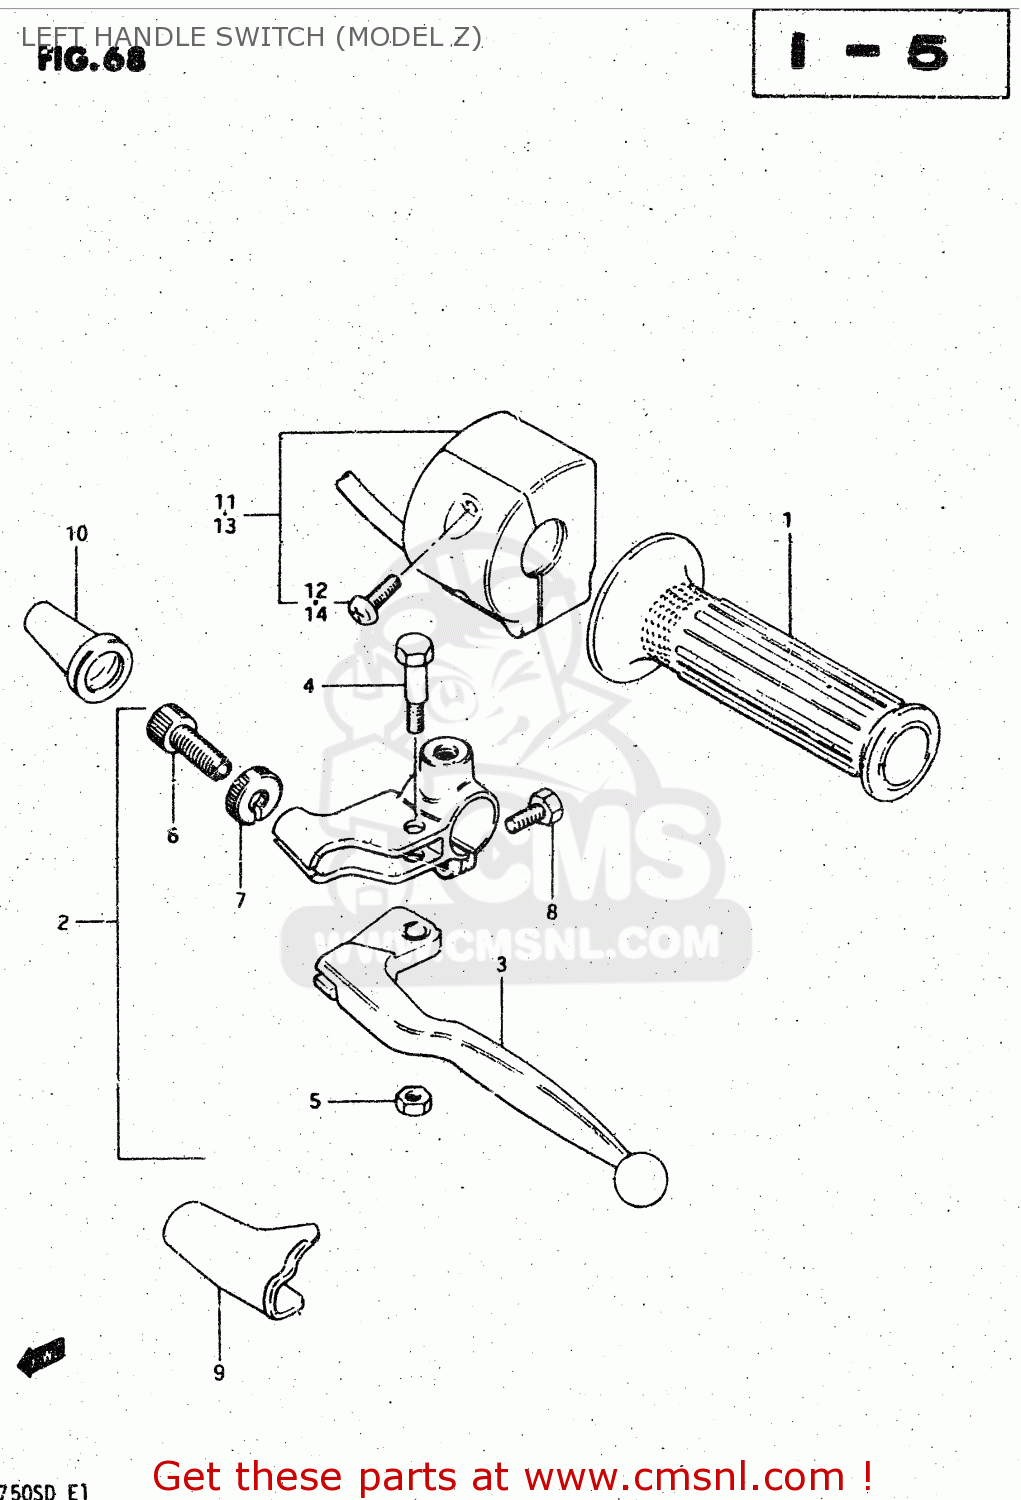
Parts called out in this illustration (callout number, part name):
1	GRIP,LEFT
2	LEVER ASSEMBLY
3	LEVER,CLUTCH
4	BOLT,LEVER
5	NUT 6MM
6	ADJUSTER,CABLE
7	NUT,CABLE ADJUSTER
8	BOLT,CLUTCH LEVER HOLDER
9	COVER,CLUTCH LEVER
10	BOOT,CLUTCH CABLE
11	SWITCH ASSY, HANDLE LH
12	SCREW
13	SWITCH ASSY, HANDLE LH
14	SCREW
